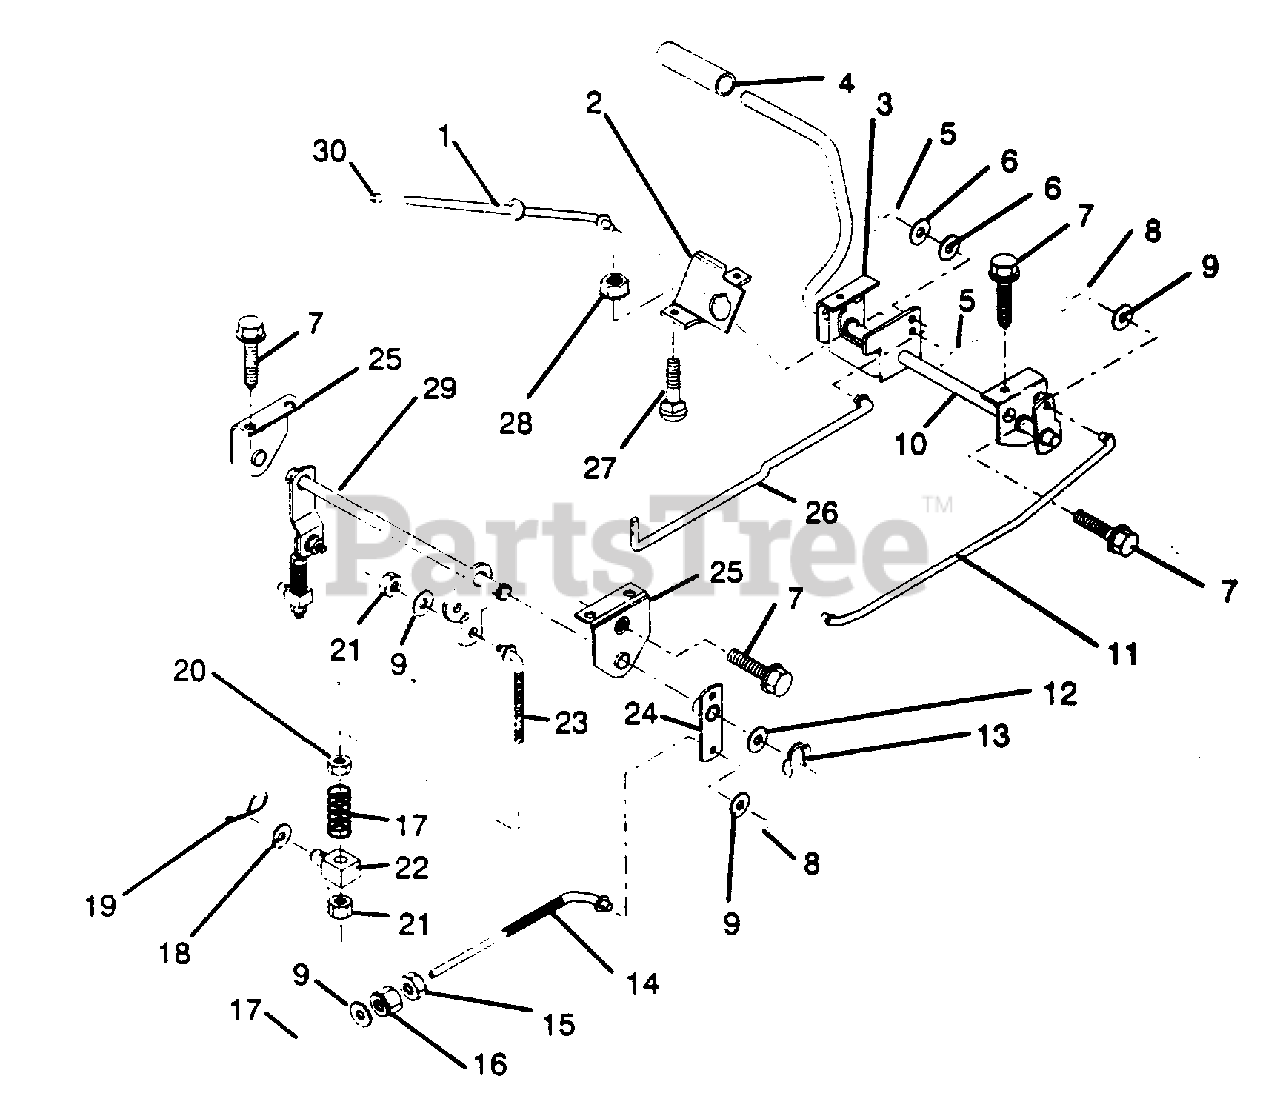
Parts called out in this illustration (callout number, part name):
1	Rod, Parking Brake
2	Bracket, Parking Brake
3	Bracket, L.H. Clutch Pedal
4	Cover, Pedal
5	Pin, Cotter 3/32 x 3/4
6	Washer, 13/32 x 5/8 x 16 Ga.
7	Screw, Hex Washer Hd. TF 5/16-18 x 1/2
8	Pin, Cotter 1/8 x 3/4
9	Washer 13/32 x 13/16 x 16 Ga.
10	Assembly, Clutch/Brake Pedal
11	Rod, Front Brake
12	Washer 25/32 x 1-1/8 x 16 Ga.
14	Rod, Rear Brake
15	Nut, Hex Jam 3/8-16 UNC
16	Nut, Lock, Hex with Wsh Insert 3/8-16 UNC
17	Spring, Brake Rod
18	Washer 13/32 x 1 1/4 x 12 Ga.
19	Spring, Retainer
20	Nut, Centerlock 3/8-16 UNC
21	Nut, Crownlock 3/8-16 UNC
22	Trunnion, Lift
23	Link, Threaded
24	Assembly, Brake Pivot Arm
25	Bracket, Lift Shaft
26	Rod, Clutch
27	Bolt, Carriage 5/16-18 UNC x 3/4
28	Nut, Keps 5/16-18 UNC
29	Assembly, Rear Mower Lift
